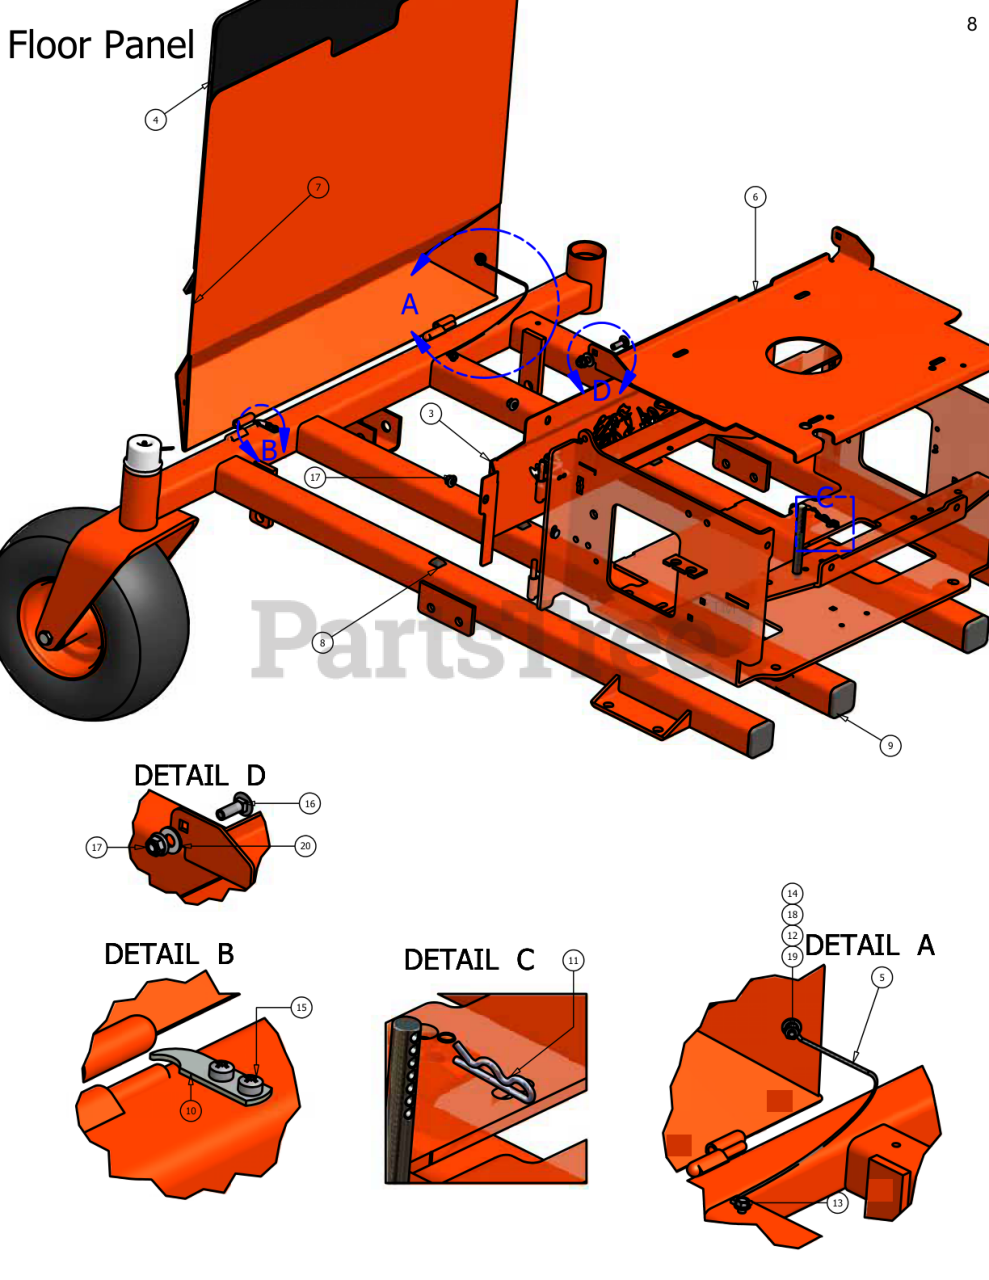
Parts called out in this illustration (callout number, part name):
1	Suspension Seat (All Lightning)
2	EVC Seat (23hp and 30hp Pup Models)
3	Cooler Cover
4	Pup Floor Mat
5	Floor Board Cable
6	Seat Plate
7	Pup Floor Panel
8	Floor Rubber Bumper
9	Frame Plug
10	Floor Panel Stop
11	#9 Hit clip (seat latch)
12	1/4" Flat Washer
13	1/4" x 1" Self Tapping Screw
14	1/4" x 5/8" Button Head Bolt
15	#10 x 1/2" Self Taping Screw
16	5/16" x 1" Carriage Bolt
17	5/16" Nylock Flange Nut
18	1/4" Hex Nut
19	1/4" Lock Washer
20	.360 ID Plastic Washer
